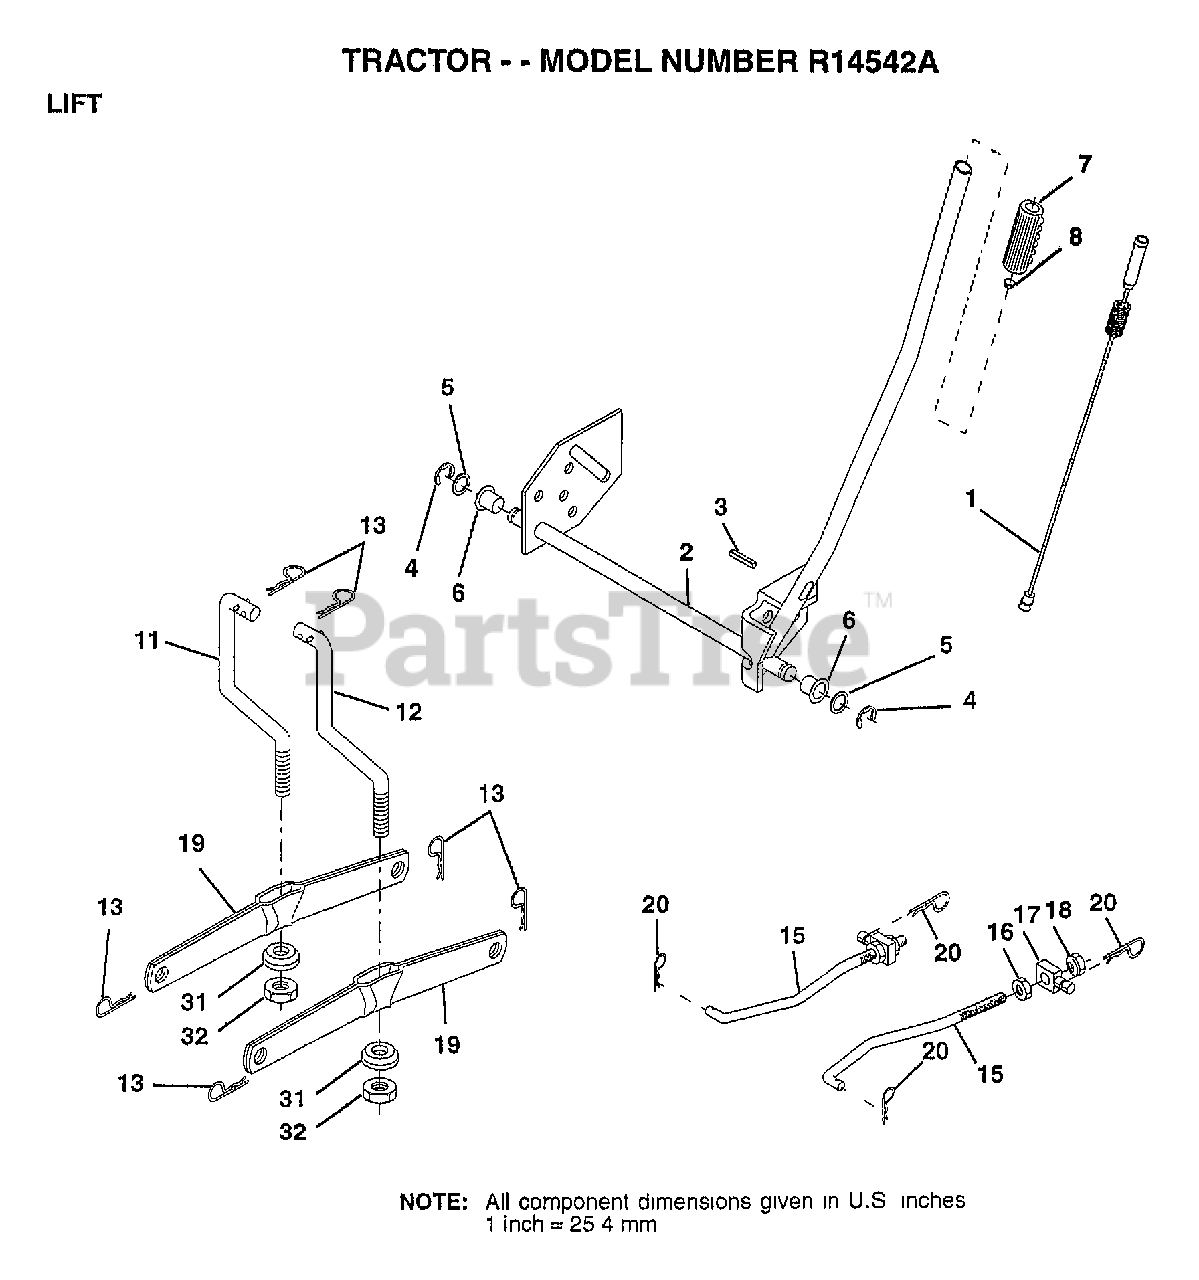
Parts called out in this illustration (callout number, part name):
1	WIRE.ASM.INNER.SP
2	"SHAFT AMS LIFT,RH"
3	PIN GROOVE
5	WASHER
6	NYLON BEARING
7	GRIP
15	LINK.FRONT
16	NUT
17	TRUNION
18	NUT.LK.W/WSH.1/2.
19	ARM SUSP REAR
20	RETAINER.SPRING
31	BEARING PVT LH
32	NUT.CROWNLOCK.3/8
